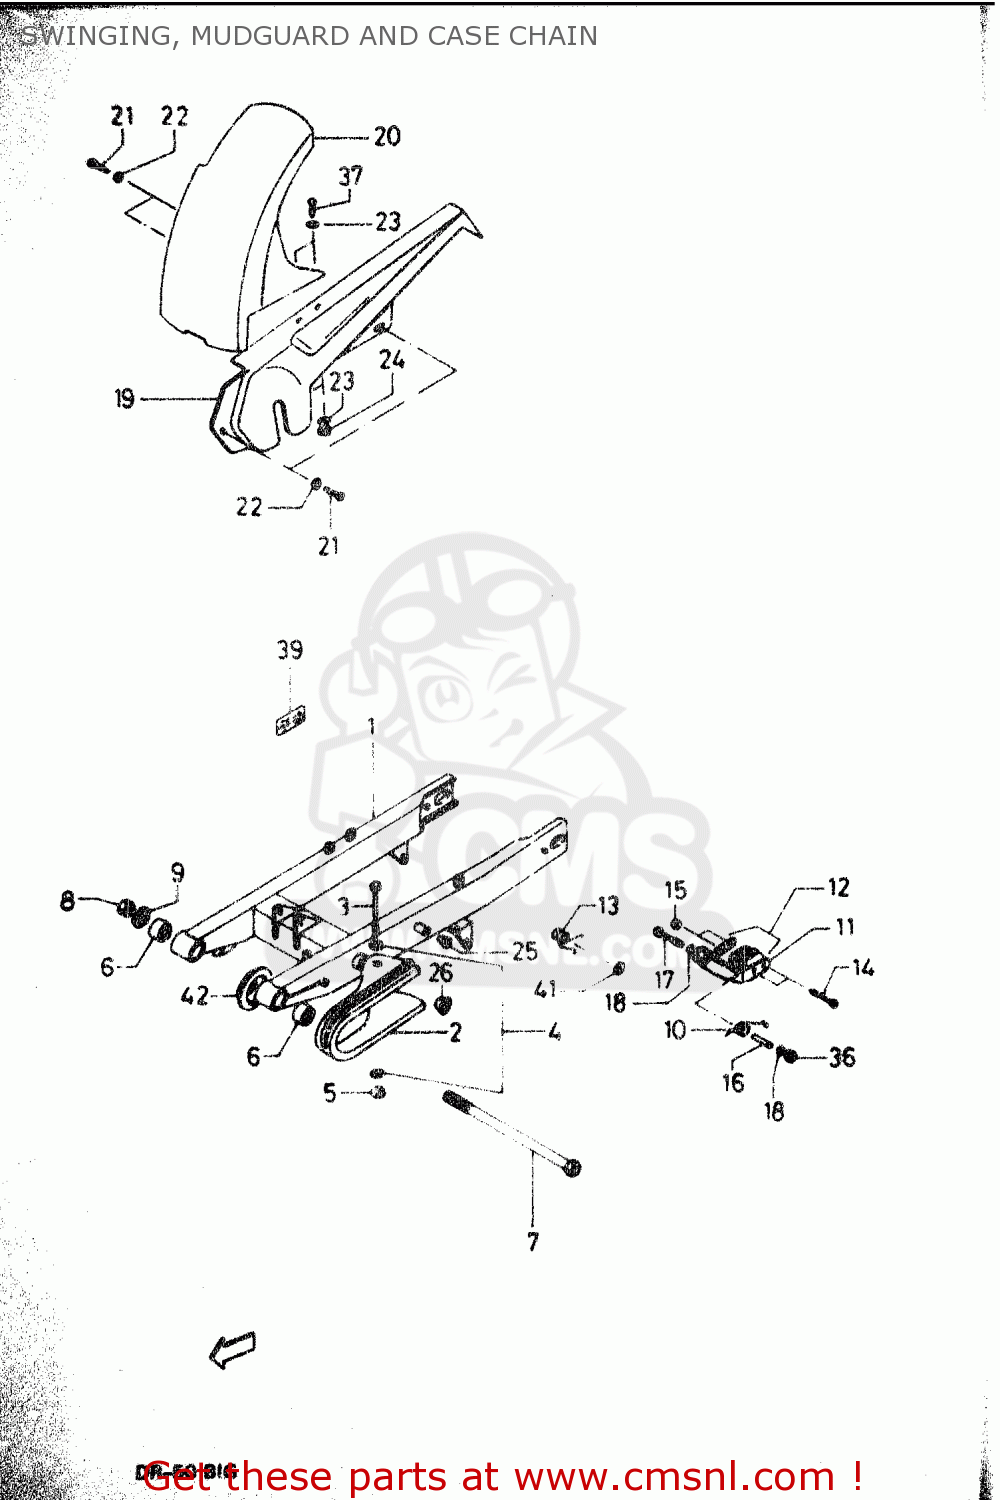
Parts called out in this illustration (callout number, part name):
1	SWINGING ARM ASSY, REAR (SILVER)
2	BUFFER, CHAIN TOUCH DEFENSE
3	SCREW M6X60 DIN 931
4	WASHER 6 DIN 9021
5	NUT M6 DIN 985
6	FLEXIBLOC
7	SHAFT
8	NUT
9	WASHER B12 DIN 125
10	GUIDE,CHAIN
11	GUIDE,CHAIN
12	ROLLER, CHAIN
13	SPRING, CYCLE CHAIN TENSIONER
14	SCREW M4X30 DIN 933
15	NUT M4 DIN 985
16	SPACER
17	SCREW M6X30 DIN 931
18	WASHER B6 DIN 125
19	CASE, CHAIN
20	MUDGUARD, REAR
21	SCREW M5X12 DIN 7985/N
22	WASHER 5 DIN 9021
23	WASHER B5 DIN 125
24	NUT
36	NUT M6 DIN 985
37	SCREW M5X15 DIN 7985
39	ADHESIVE, CHAIN
40	E RING (E 16 DIN 471)
41	WASHER (16.1X25.6X2)
42	FINISHING WASHER
